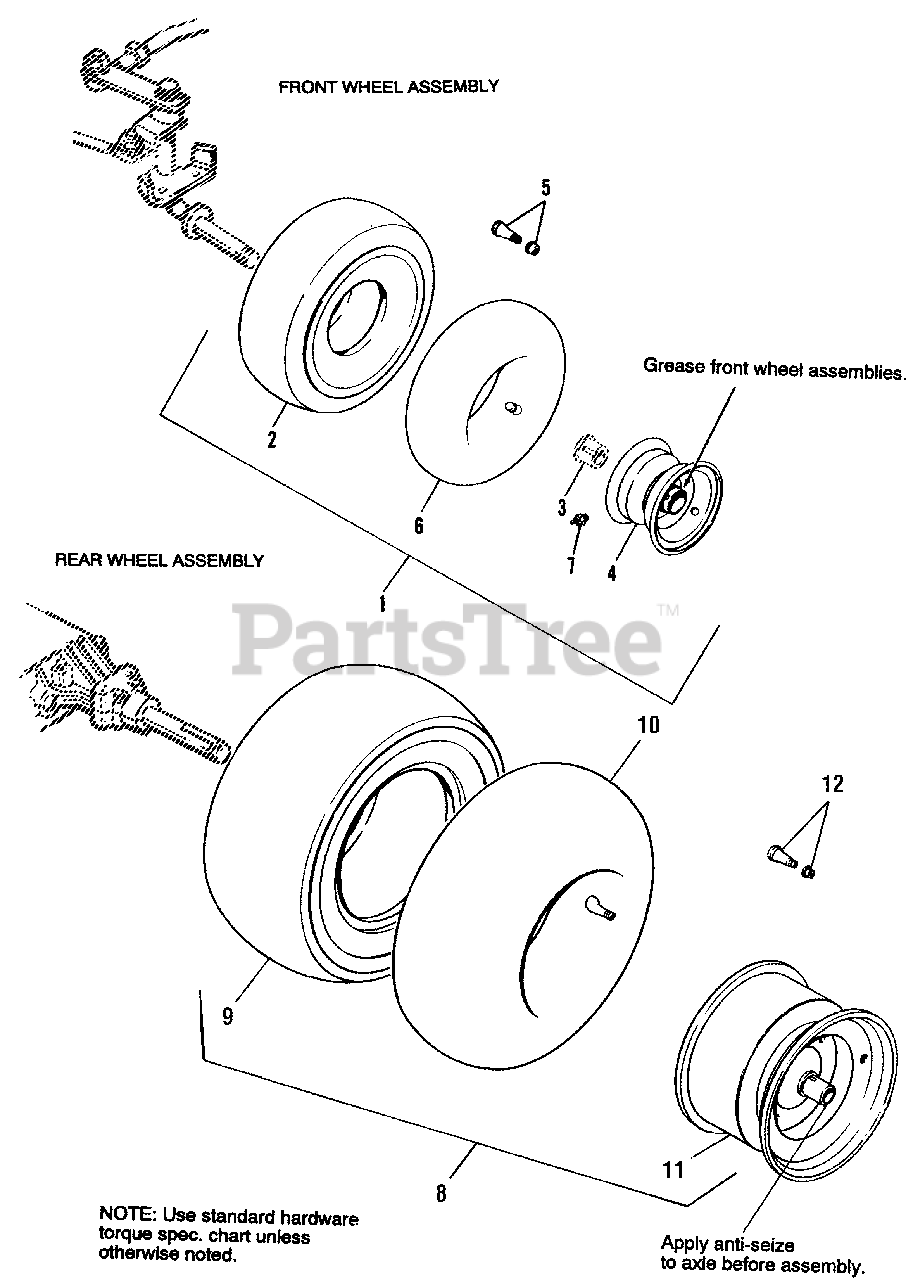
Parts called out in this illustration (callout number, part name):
1	WHEEL & TIRE ASSY.15 x 6.00-6, Beige (Includes Ref. Nos. 2, 3, 4, 5 & 6.)
1	WHEEL & TIRE ASSY.15 x 6.00-6, Silver (Includes Ref. Nos. 2, 3, 4, 5 & 6.)
2	TIRE, 15 x 6.00-6
3	BEARING
4	WHEEL ASSY., Beige (Incl. Ref. No.3)
4	WHEEL ASSY., Silver (Incl. Ref. No. 3)
5	VALVE STEM & CAP
6	TUBE, 4.10/3.50-6 (Service only)
7	GREASE FITTING
8	WHEEL & TIRE ASSY., 20 x 8.00-10, Beige (Used on 15 HP Gear & 16 HP Hydro models) (Includes Ref. Nos. 9, 10, 11 & 12)
8	WHEEL & TIRE ASSY., 20 x 8.00-10, Silver (Used on 15 HP Gear & 16 HP Hydro models) (Includes Ref. Nos. 9, 10, 11 & 12)
8	WHEEL & TIRE ASSY., 18 x 8.50-8, Beige (Used on 12.5 & 14 HP Hydro models) (Includes Ref. Nos. 9, 10, 11 & 12)
8	WHEEL & TIRE ASSY., 18 x 8.50-8, Silver (Used on 12.5 & 14 HP Hydro models) (Includes Ref. Nos. 9, 10, 11 & 12)
9	TIRE, 20 x 8.00-10
9	TIRE, 18 x 8.50-8
10	TUBE, For 20 x 8.00-10 Tire (Service only)
10	TUBE, For 18 x 8.50-8 Tire (Service only)
11	WHEELASSY., 10" Dia., Beige
11	WHEELASSY., 10" Dia., Silver
11	WHEELASSY., 8" Dia., Beige
11	WHEEL ASSY., 8" Dia., Silver
12	VALVE STEM & CAP, Used on 10" Dia. Wheels
12	VALVE STEM & CAP, Used on 8" Dia. Wheels
